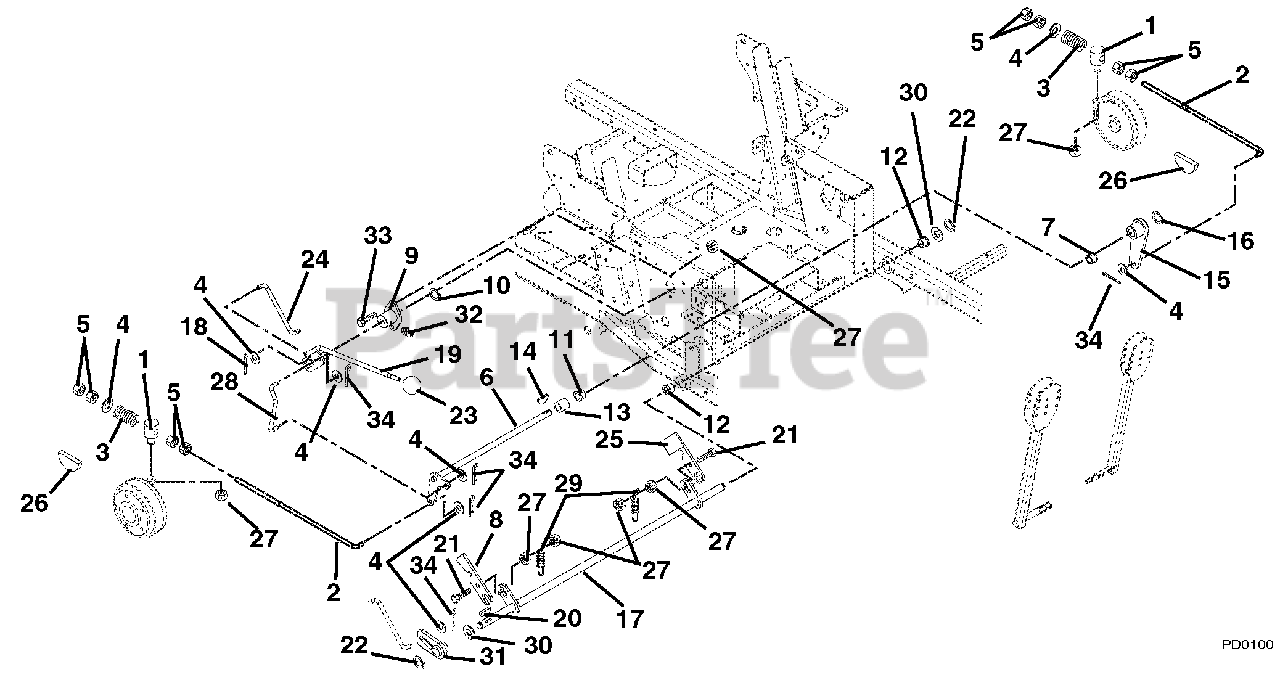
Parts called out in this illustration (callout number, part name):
1	Pivot, Brake Rod
2	Rod, Brake .38 x 19.00
3	Spring, Compression .143 x .71 x 2.00
4	Washer, Flat Steel .406 x .812 x .065
5	Nut, Hex .38-16
6	Shaft, Brake Cross
7	Bushing, Flange Nylon .63 x 1.00 x .625
8	Slide, Interlocking Brake
9	Bushing, Flange
10	Ring, Retaining External .625 x .05
11	Bushing, Flange Nylon .762 x 1.00 x .58 x 1.48
12	Bushing, Flange .50 x .75 x .75 x 1.00
13	Bushing, Sleeve .75 x 1.00 x .75
14	Key, Woodruff .19 x .75 Hard #9
15	Arm, Brake Left Hand
16	Ring, Retaining External .625 x .050
17	Weldment, Mechanical Brake
18	Pin, Cotter External .09 x .75
19	Weldment, Brake Actuating
20	Key, Woodruff .13 x .63
21	Bolt, Hex .31-18 x 1.25 Grade 5
22	Ring, Retaining External .50 x .05
23	Knob, Steering Lock
24	Linkage, Brake Actuating
25	Interlock, Safety Switch
26	Pad, Disk Brake
27	Nut, Locking, Top Flange .31-18
28	Linkage, Brake Actuating
29	Spring, Tension .063 x .44 x 1.56
30	Washer, Flat Steel .505 x 1.00 x .062
31	Weldment, Parking Brake Hub
32	Fitting, Lube .25-28 x .256
33	Bolt, Hex .31-18 x .75 Grade 5
34	Pin, Hair
